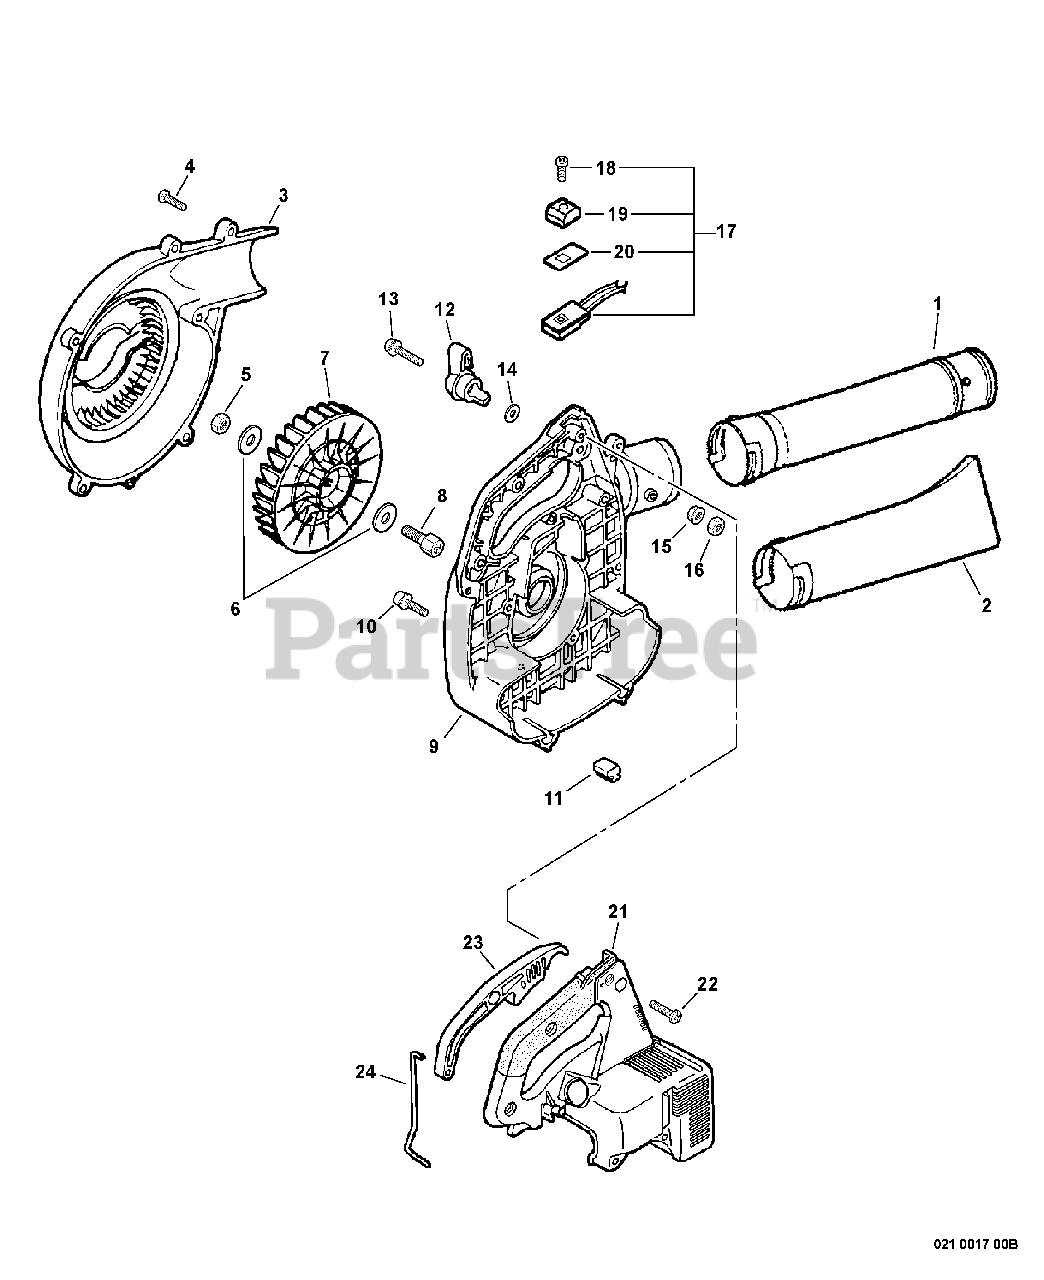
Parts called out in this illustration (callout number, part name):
1	TUBE, BLOWER - STRAIGHT
2	TUBE, BLOWER - NOZZLE
3	COVER, FAN - LEFT
4	SCREW - 5X20 -- TAPPING
6	WASHER - 8
8	HUB, FAN
9	COVER, FAN - OUTER
10	SCREW - 4X22
12	LEVER, THROTTLE - ORANGE
13	SCREW - 5X25
14	WASHER - 5
15	NUT - 5 -- FLANGE
17	IGNITION SWITCH ASSY
18	SCREW - 3X10
19	KNOB, SWITCH - ORANGE
20	COVER, SWITCH - STOP
21	COVER, ENGINE - GRAY
22	SCREW - 5X20 -- TAPPING
23	TRIGGER, THROTTLE - ORANGE
24	ROD, THROTTLE
